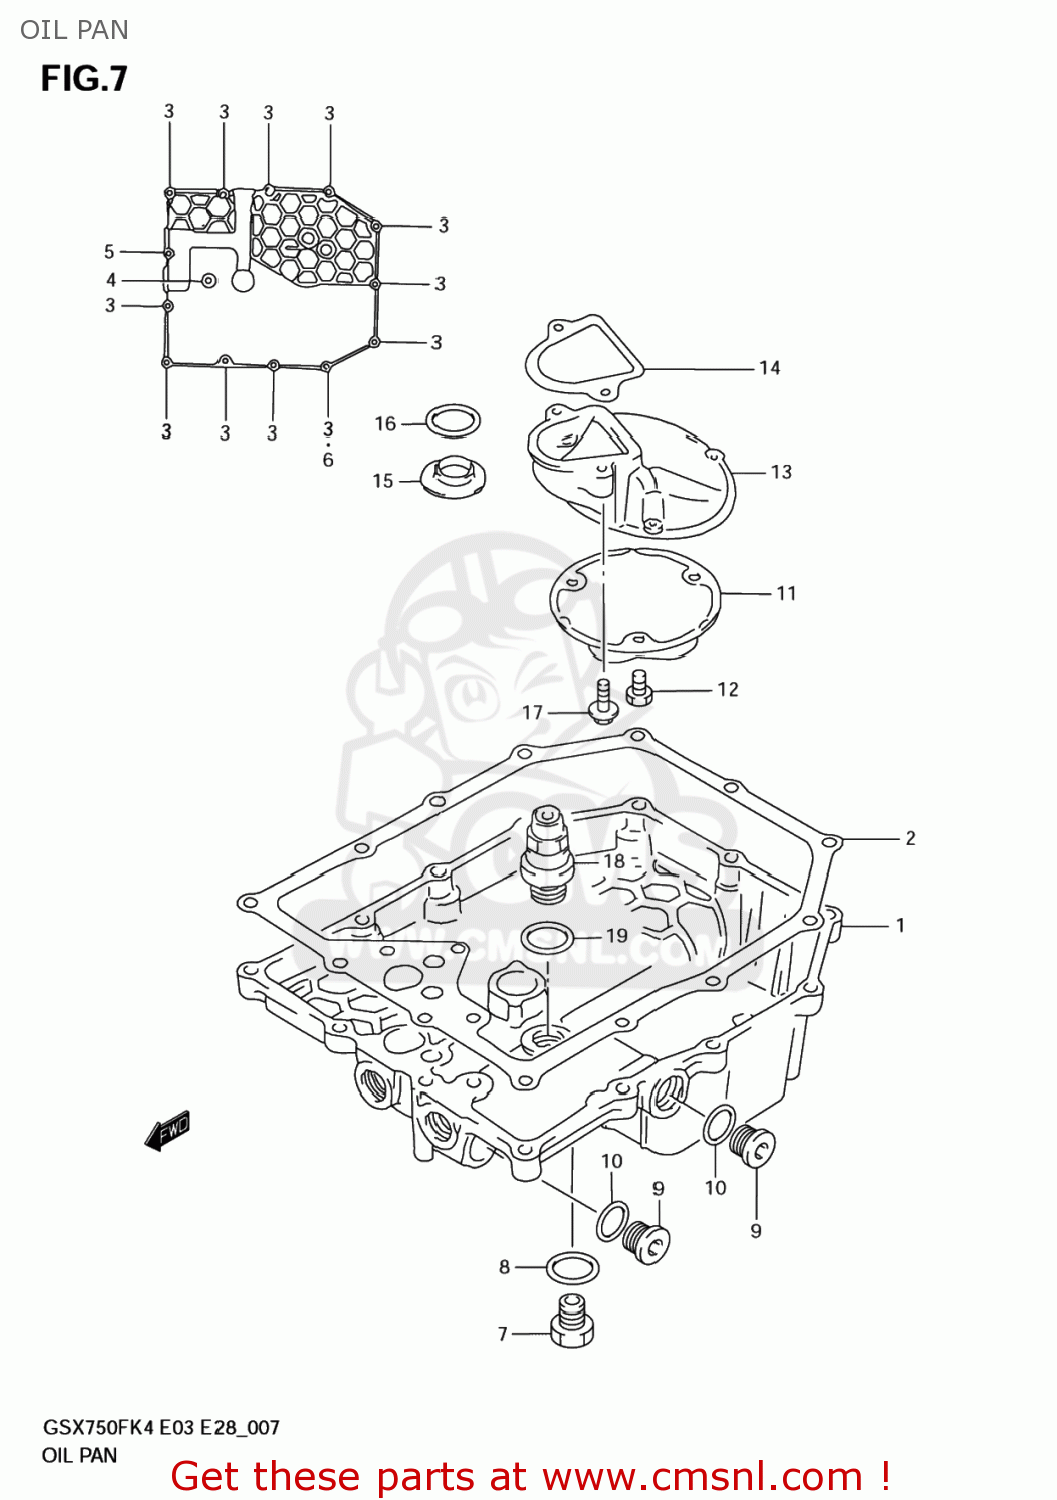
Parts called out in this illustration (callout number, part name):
1	PAN,OIL
2	GASKET,OIL PAN(ASB) (NAS)
3	BOLT
4	BOLT
5	BOLT
6	GASKET(5.8X13X1.2) (NAS)
7	PLUG(14X12)
8	GASKET(13.8X18.8X4.8) (NAS)
9	PLUG,16X8
10	GASKET(16X22X2) (NAS)
11	STRAINER,ENGINE OIL
12	BOLT
13	PROTECTOR,OIL STRAINER
14	GASKET,OIL STR PROTECTOR (NAS)
15	GASKET,OIL OUTLET (NAS)
16	O RING(D:3.2,ID:17.8)
17	BOLT
18	VALVE ASSY,OIL RELIEF
19	GASKET(16X22X2) (NAS)
